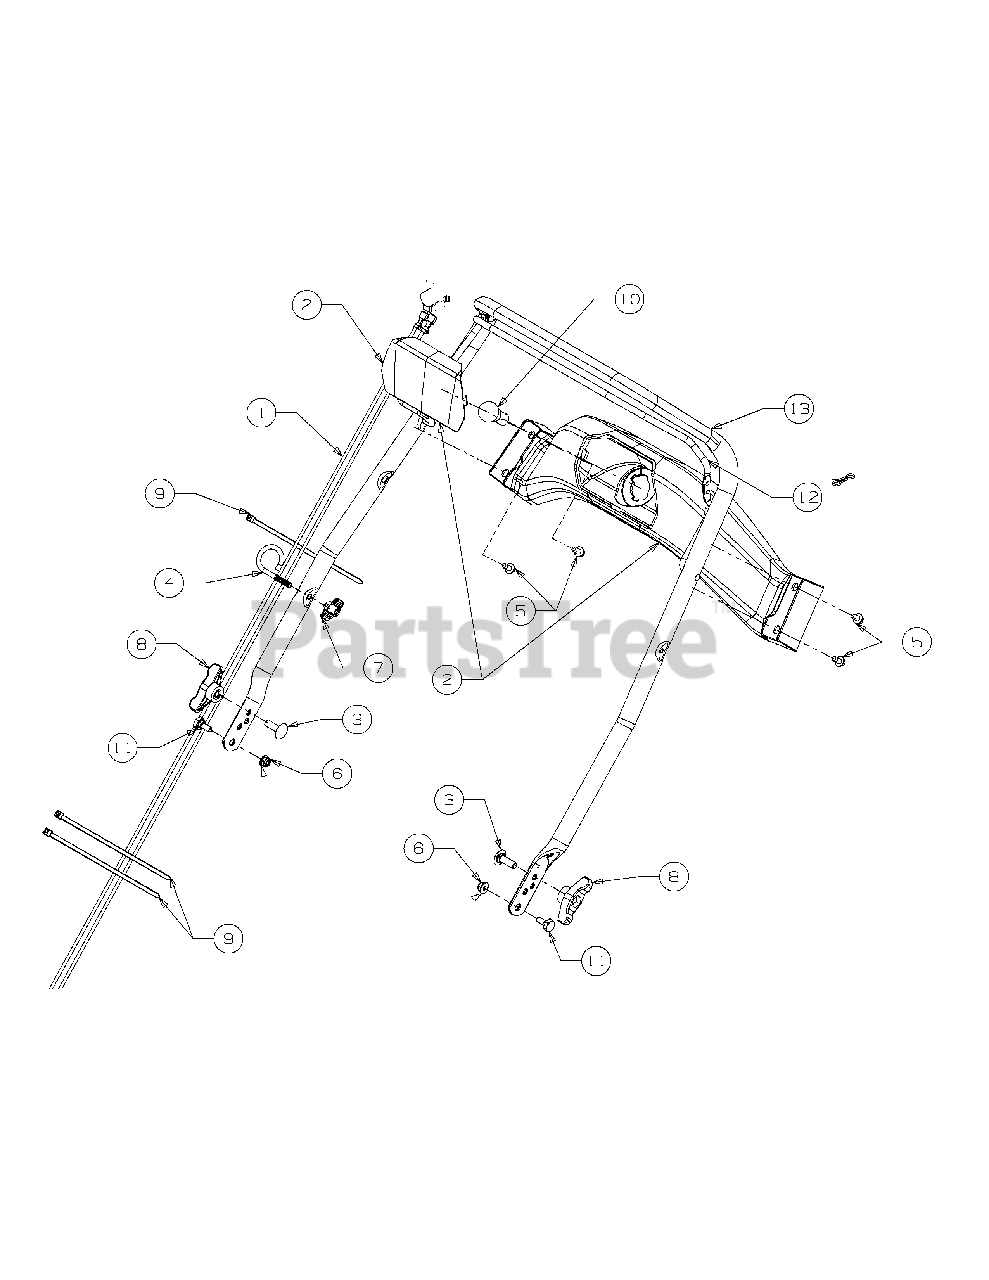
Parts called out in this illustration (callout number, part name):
1	Harness Assy-Li
2	Panel Asm-Handl
3	Screw-Carriage 5/1
4	Eyebolt 1/4-20
5	Screw-Hex Wash Sf
6	Nut-Flglk
7	Handle Knob
8	Knob-Wing 5/16-18
9	Tie-Cable 7"
10	Lamp:#Ll41
12	Bail-Auger
13	Hndl:Upr:Gullwing Adu
